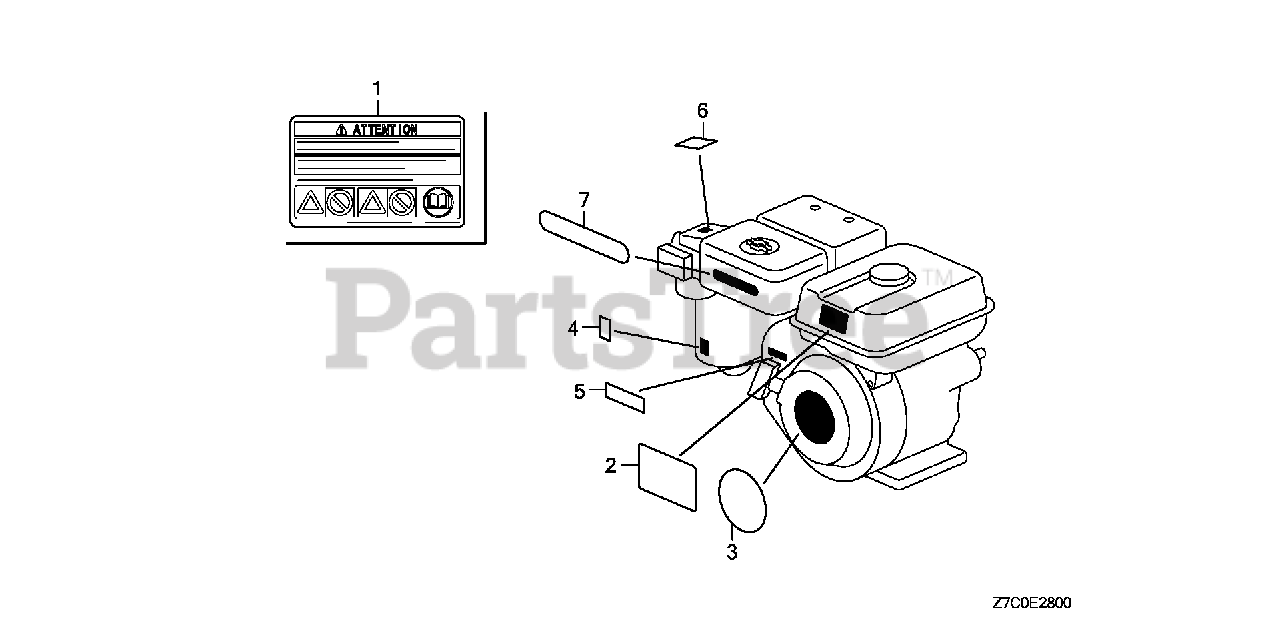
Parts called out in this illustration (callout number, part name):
1	MARK, OPERATOR CAUTION (FRENCH)(MADE IN JAPAN)
1	MARK, OPERATOR CAUTION (FRENCH)
2	MARK, OPERATOR CAUTION (ENGLISH)
3	EMBLEM (GX270)
4	MARK, CHOKE
5	MARK, THROTTLE INDICATION
6	LABEL, AIR CLEANER CAUTION
7	MARK, AIR CLEANER SALES POINT
